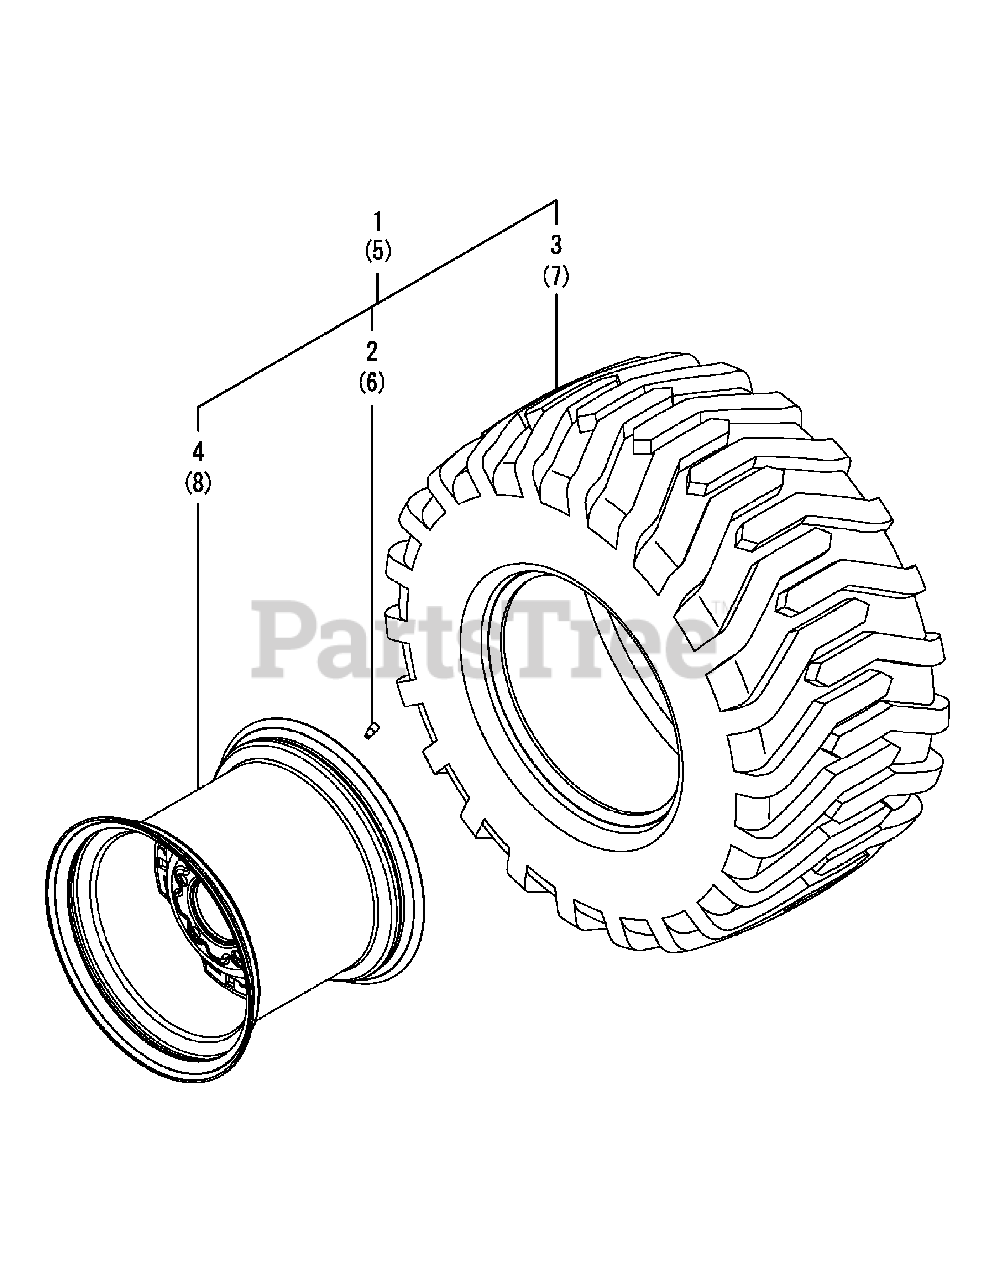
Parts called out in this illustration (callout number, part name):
1	R4 REAR TIRE L KIT
3	TIRE, 26X12-12 R4
5	R4 REAR TIRE R KIT
7	TIRE, 26X12-12 R4
